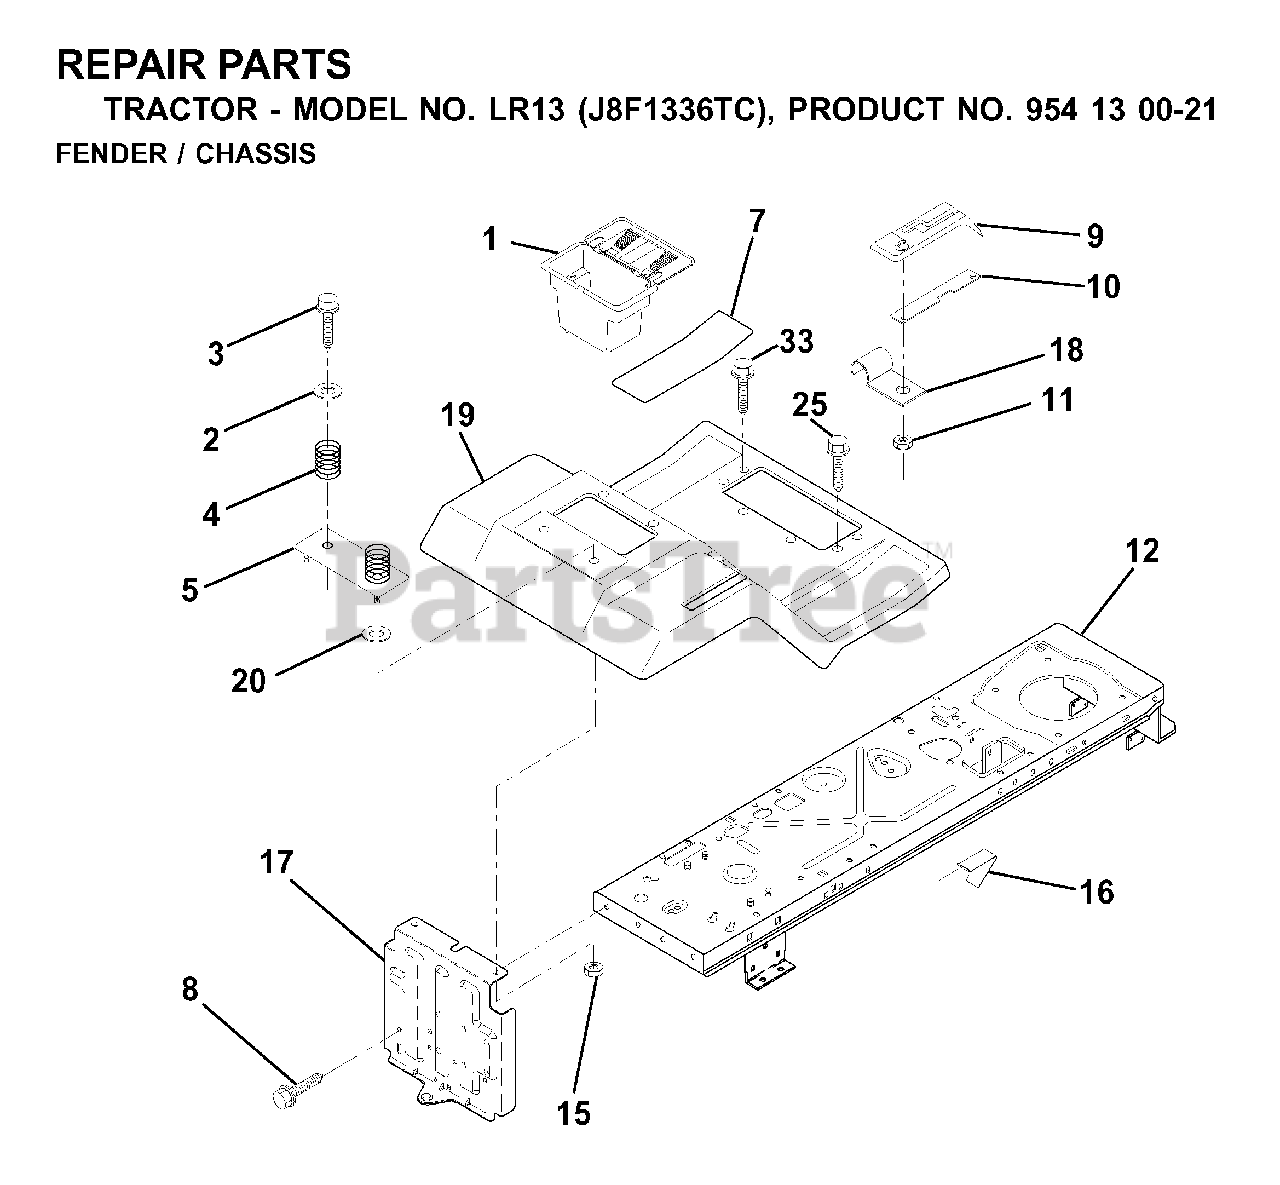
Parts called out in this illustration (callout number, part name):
1	CASE BATTERY MECH HINGE
3	SCREW
4	SPRING COMPRESSION
7	PAD FOOTREST
8	SCREW
10	BAR, SHIFT LOCK
18	CLIP,INSULATOR
20	WASHER
34	SHOULDER BOLT 5/16-18TT
